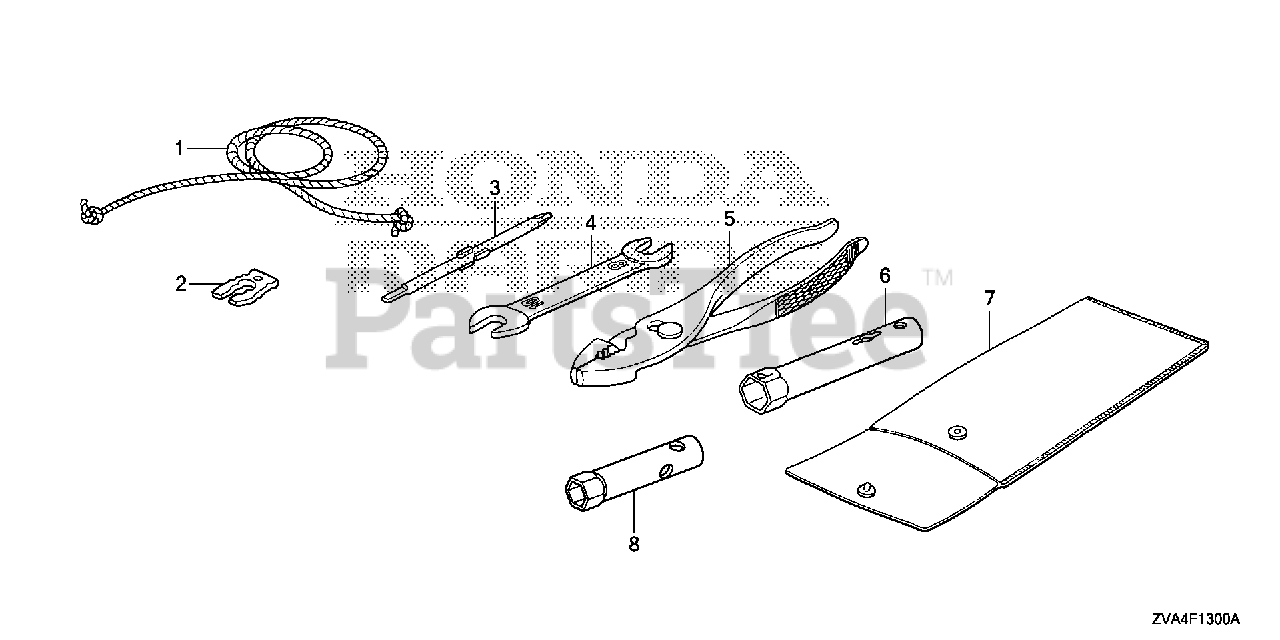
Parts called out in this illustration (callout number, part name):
1	ROPE, STARTER
2	CLIP, EMERGENCY LOCK
3	SCREWDRIVER (NO.2 +/-) (SOURCE: VINTAGE PARTS INC.)
4	SPANNER (8X10)
6	WRENCH, BOX (P16)
7	BAG, TOOL (160MM)
8	WRENCH, BOX (10MM)
